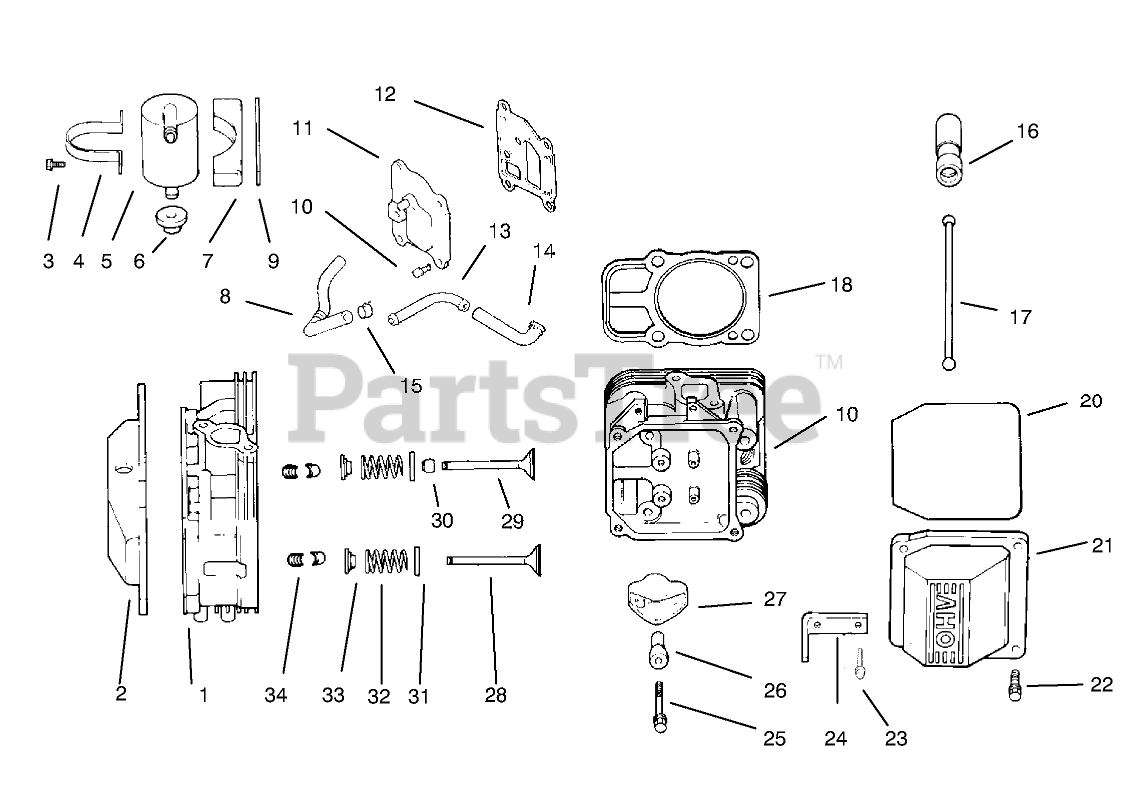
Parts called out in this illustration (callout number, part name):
1	#1 Cyl. Head Asm
2	Kit-Valve Incl 6 20-22
3	Screw-HF
4	Strap-Lifting
5	Kit-Breather Incl 3-9
6	Grommet-Rubber
7	Bracket
8	Hose-Breather
9	Spacer
10	Screw
11	Cover-Breather
12	Gasket-Breather
13	Fitting
14	Hose-Breather
15	Clamp
16	Lifter-Valve
17	Rod-Push
18	Gasket-Cylinder Head
19	#2 Cyl. Head Asm,
20	O Ring
21	Valve Kit
22	Screw
23	Screw
24	Strap-Lifting
26	Pivot-Arm, Rocker
27	Arm-Rocker
28	Valve-Exhaust
28	Valve-Exhaust (.25)
29	Valve-Intake
29	Valve-Intake (.25)
30	Seal-Stem, Valve
31	Retainer-Spring
32	Spring-Valve
33	Cap-Spring, Valve
34	Retainer Kit
